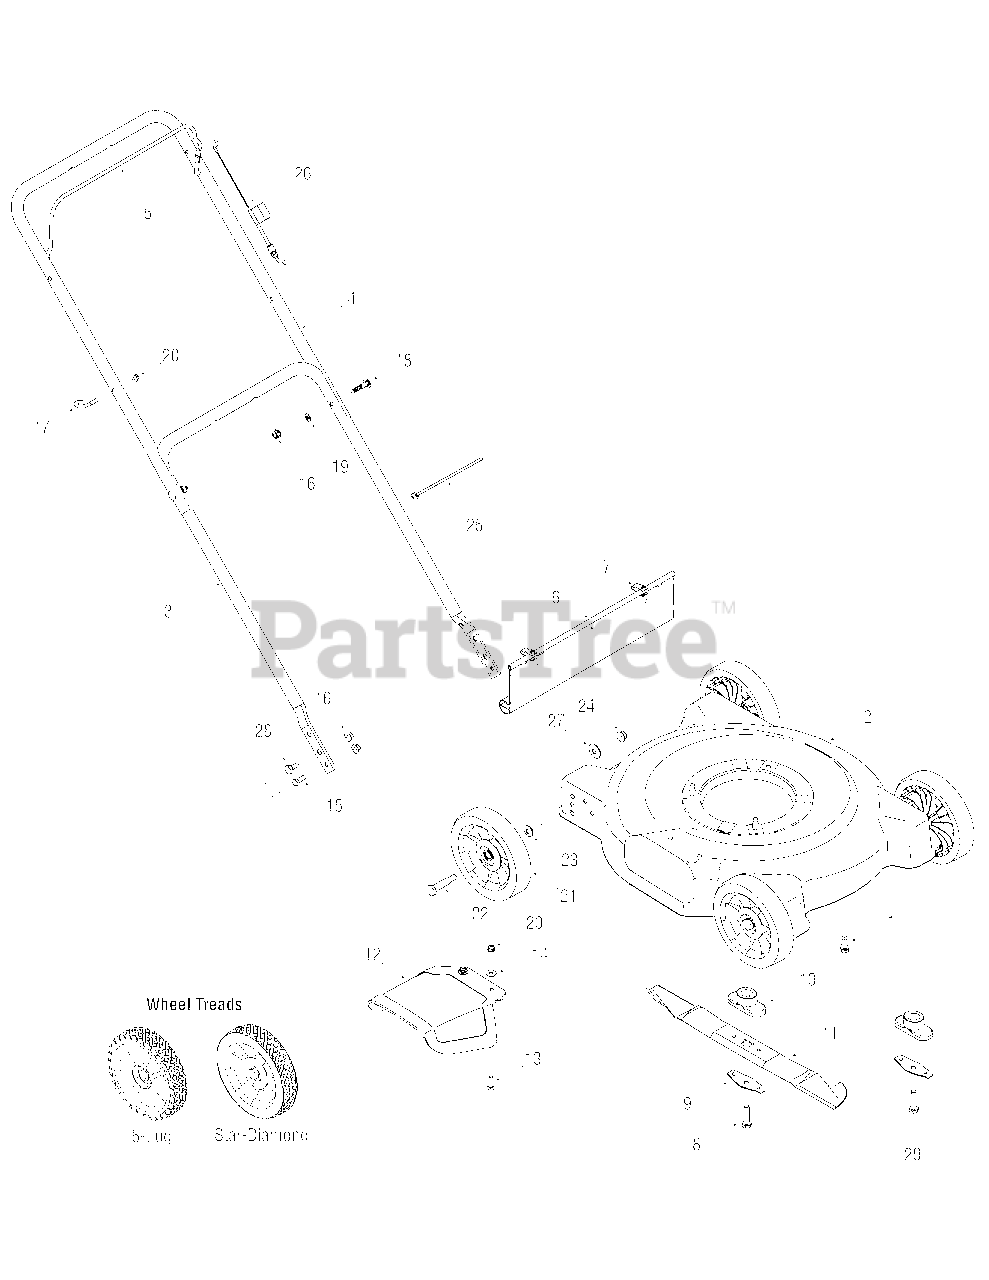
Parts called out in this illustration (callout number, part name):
1	Hex Ind. Washer Screw 3/8-16 x 1.0
6	Rear Flap
7	Hinge Clip
8	Screw 3/8-24 x 1.5" Group 8
9	Blade Bell Support
10	Blade Adapter
11	Cutting Blade
12	Discharge Chute
13	Carriage Screw 1/4-20 x 1.0"
14	Flat Washer
15	Hex Screw 5/16-18 x .75"
16	Flange Lock Nut 5/16-18
17	Eye Bolt
18	Carriage Bolt 5/16-18 x 1.5"
19	Lock Washer
20	Flange Lock Nut 1/4-20
21	Wheel, 7" Star-Dia., White
21	Wheel, 7" Star-Dia., Oys. Gray
21	Wheel, 7" 5-Lug Dia., Gray
22	Shoulder Screw .498 x 1.635
23	Bell Washer
24	Flange Lock Nut 3/8-16
25	Cable Tie
26	Control Cable - 48.25"
26	Control Cable - 37.25"
27	Bell Washer
28	Shoulder Screw, 5/16-18 x.428"
29	Blade Adapter Kit (Incl. Ref. 8-10)
